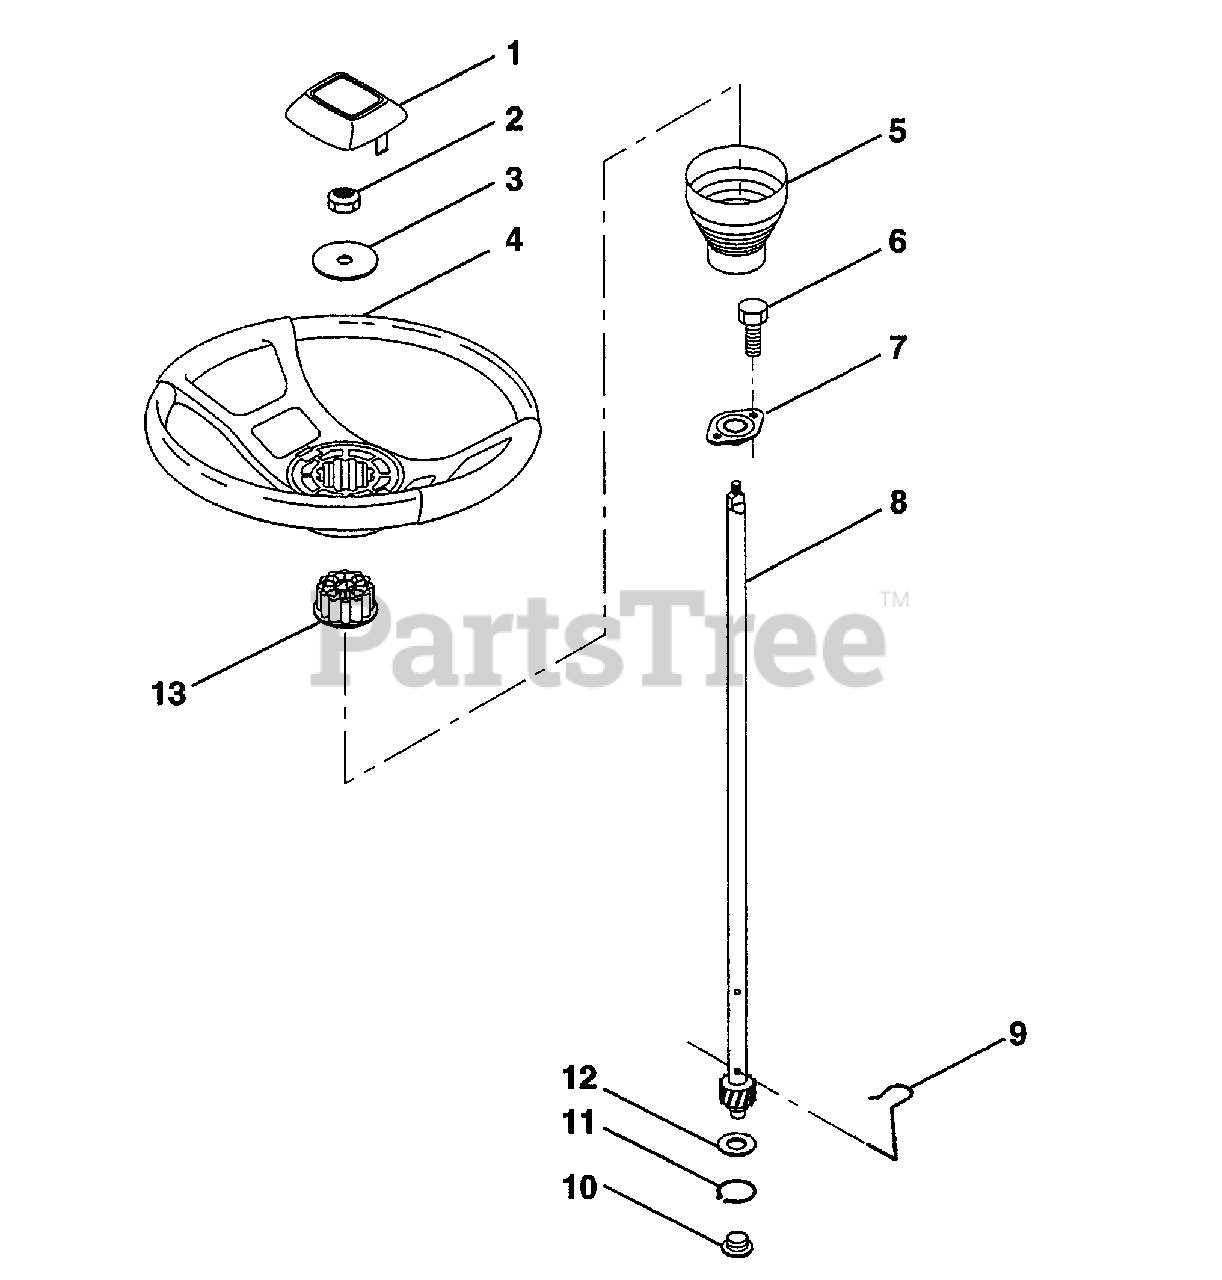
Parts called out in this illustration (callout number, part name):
1	Insert, Wheel, Steering
2	Locknut 3/8-24 UNF
3	Washer 12/32 x 2-3/8 x 8 Ga.
4	Wheel, Steering
5	Sleeve, Steering
6	Screw, Hex #10-16 x 1/2 TY-B
7	Bushing, Steering
8	Shaft, Steering
9	Clip, Steering
10	Bushing, Lower, Steering
11	Ring, Retaining
12	Washer 21/32 x 1 x 16 Ga.
13	Adaptor, Wheel, Steering
